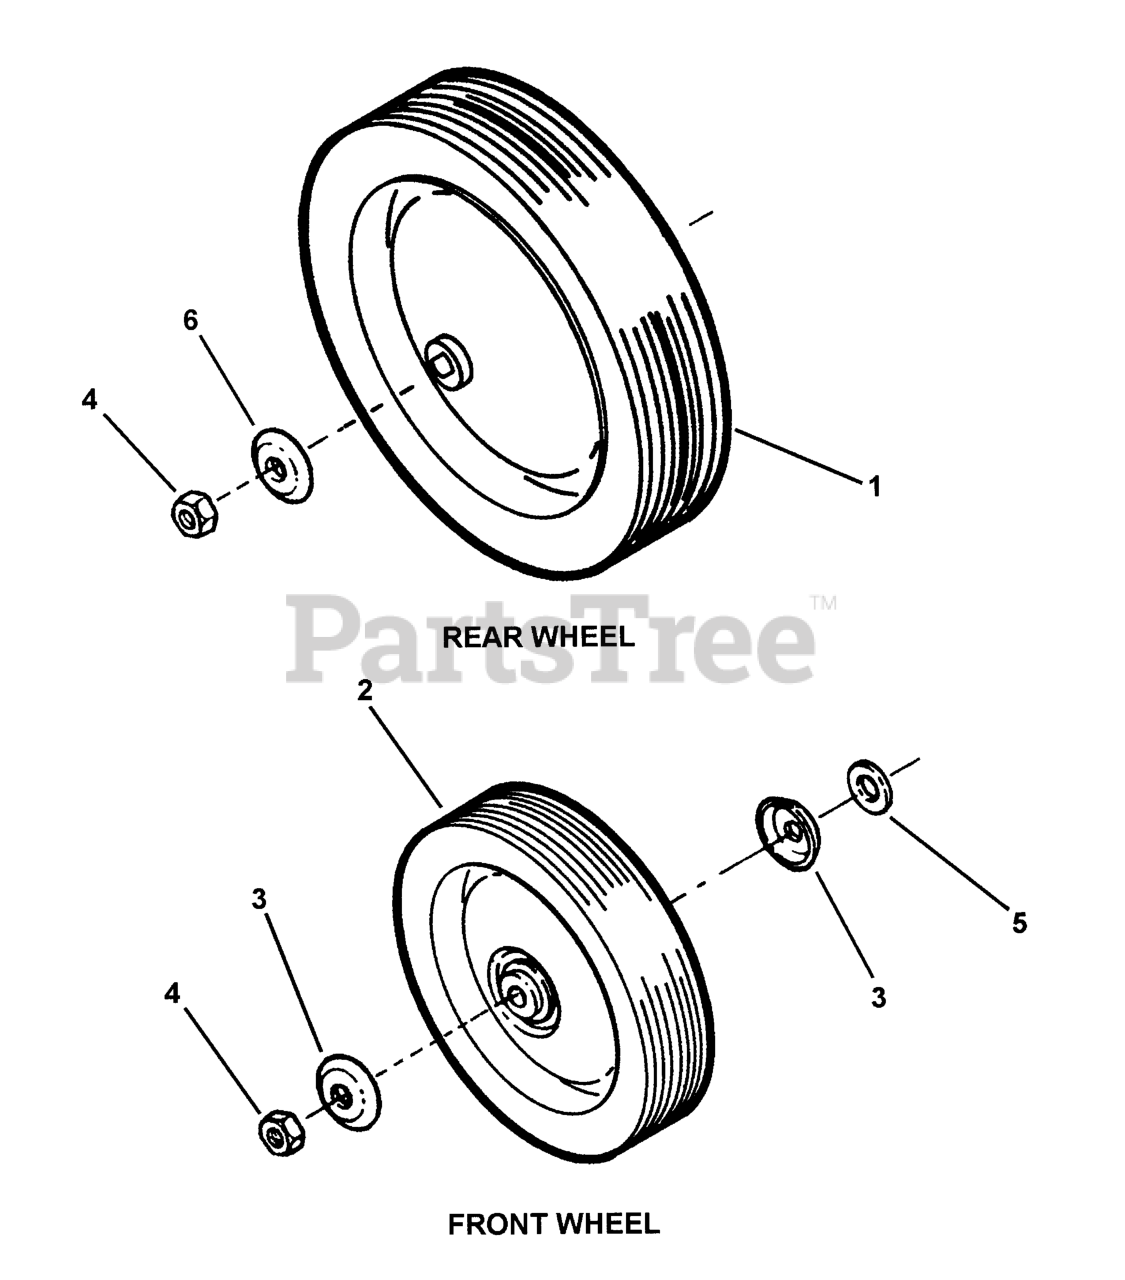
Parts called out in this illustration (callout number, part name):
1	WHEEL, Rear 10.0 x 1.75 Steel w/Diamond Tread, Gray
2	WHEEL, Front 8.0 x 1.75 Steel w/Diamond Tread, Gray
3	HUB-CAP (Front Wheels)
4	NUT, 7/16-20 Hex Center Lock Jam
5	WASHER, 7/16" Flat
6	HUB-CAP (Rear Wheels)
